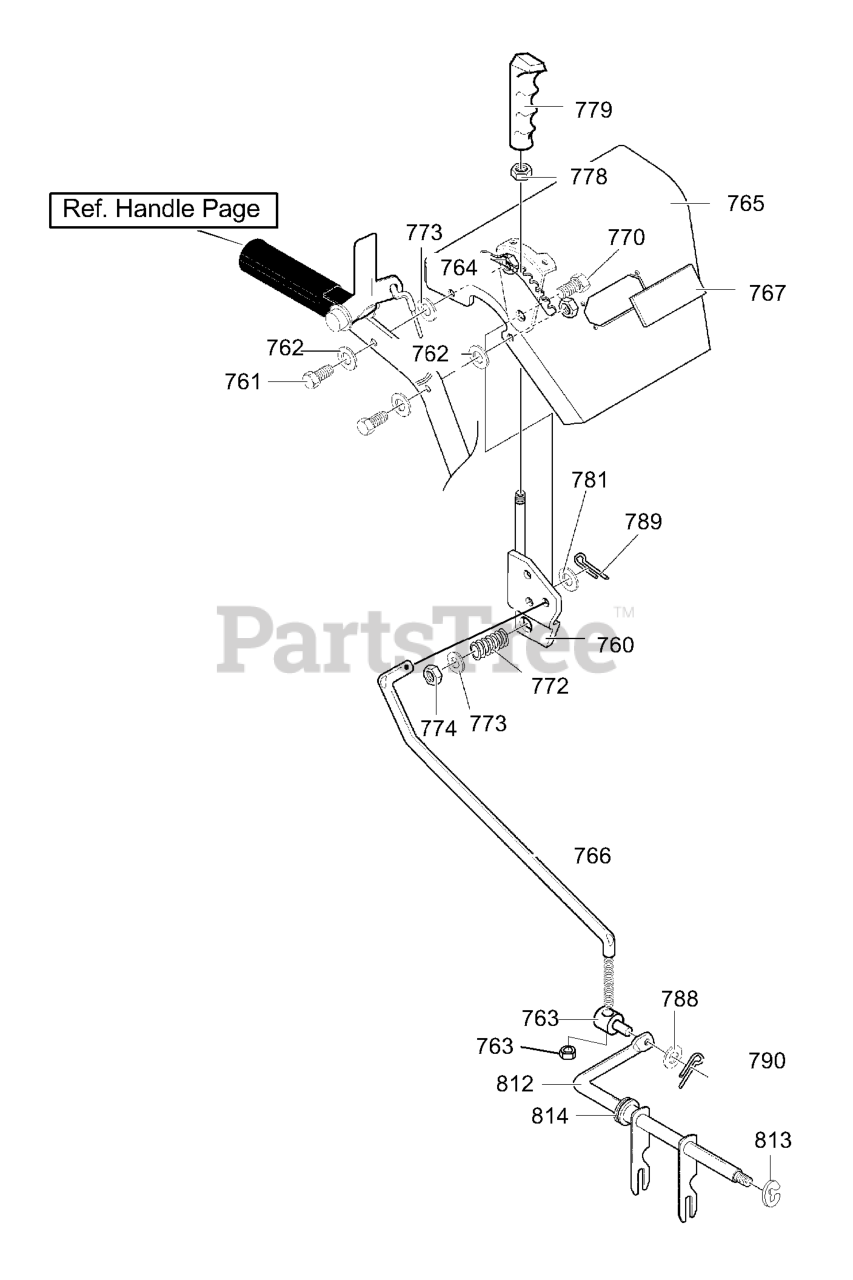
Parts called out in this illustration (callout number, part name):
760	HANDLE ASSY SPD CTRL
761	SCREW, 5/16-18 x 1.75
762	NUT, 5/16-24
763	NUT, TRUNNION
764	NUT, 5/16-18 HEXWDFLLK
765	ASSY. BAY LT
766	ROD, SPEED CONTROL
767	PLATE, BLANKING LIGHT
770	SCREW 3/8-16X2.00
773	FLATWASHER
774	NUT, 3/8-16 HEXNYL
778	NUT, 3/8-16 REGHEX
781	FLATWASHER
784	HANDLE 3/8-16
788	FLATWASHER
789	PIN, COTTER
790	COTTER PIN
812	ROD, ASSY YOKE
813	RING, RETAINER
814	BEARING, FLANGE
